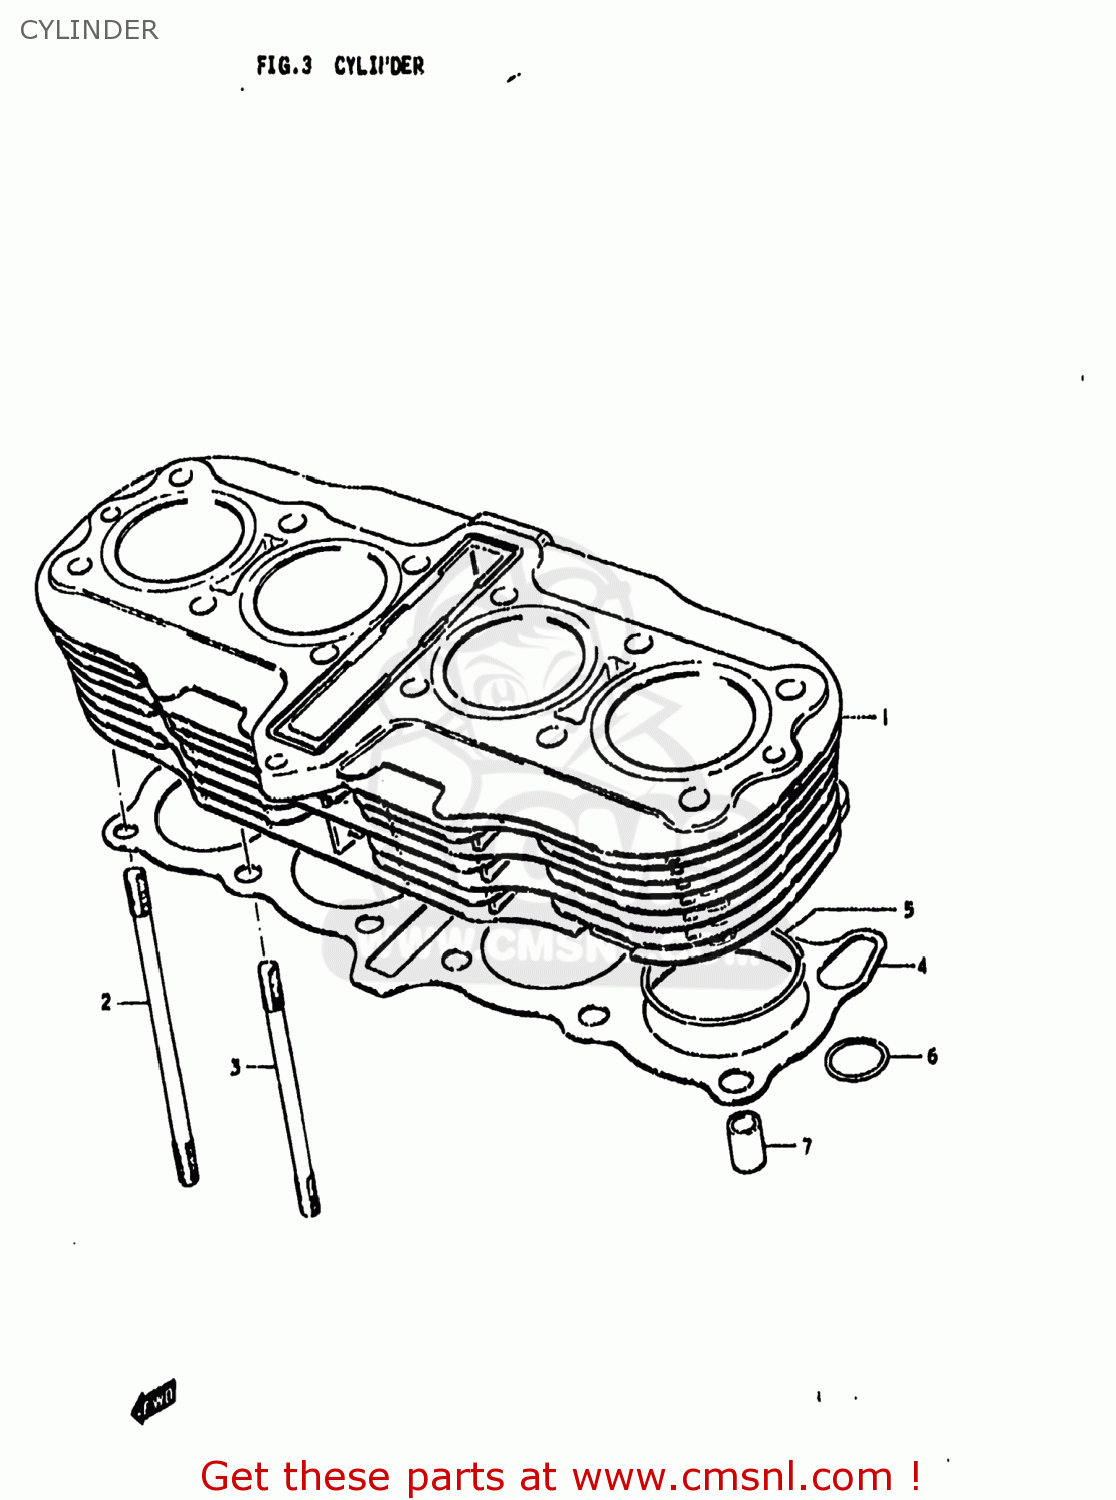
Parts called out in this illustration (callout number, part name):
1	CYLINDER
2	BOLT,STUD
3	STUD
4	GASKET,CYLINDER (MCA)
5	O RING(D:2,ID:70)
6	O RING(D:3.05)
7	PIN
